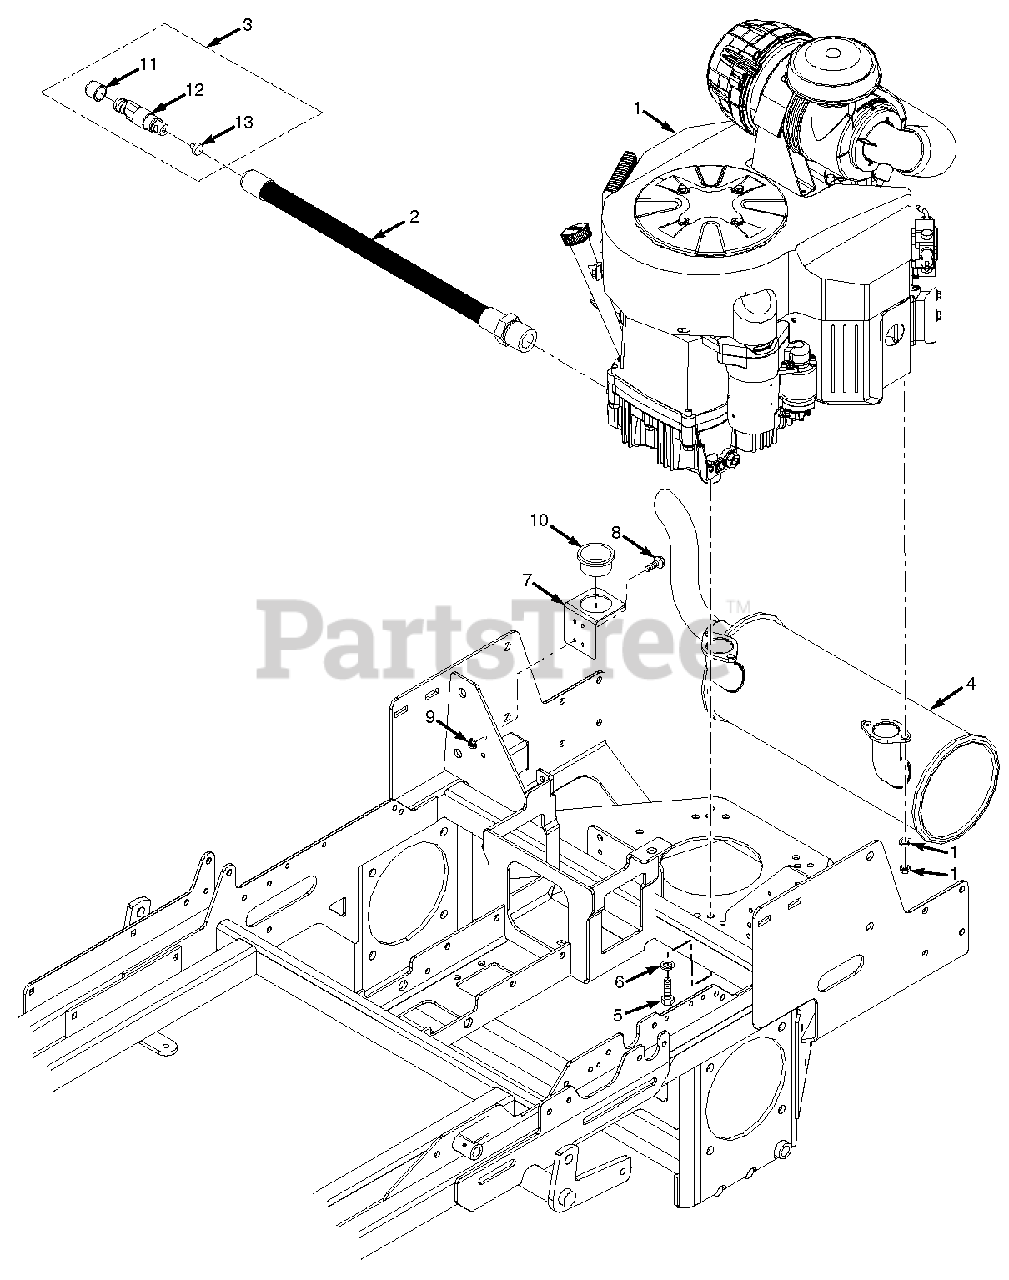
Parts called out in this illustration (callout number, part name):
1	Engine, Kawasaki 27FX (FX850)
1	Engine, Kohler 31CV-EFI (ECV860)
1	Engine, Kawasaki 31FX (FX921)
1	Engine, Kohler 35CV-EFI (ECV940)
2	Hose, Oil Drain, Kawasaki
2	Hose, Oil Drain, Kohler - ECV860
2	Hose, Oil Drain, Kohler - ECV940
3	Valve Assembly, Oil Drain
4	Muffler, Kawasaki FX850 - SCZ
4	Muffler, Kohler (ECV860)- SCZ
4	Muffler, Kawasaki FX921 - SCZ
4	Muffler, Kohler (ECV940)- SCZ
5	Bolt, Hex Head 3/8-16 x 1-1/4"
6	Lockwasher, 3/8" Spring
7	Bracket, Oil Drain Hose
8	Screw, #8-32 x 1/2"
9	Nut, Elastic Stop #8-32
10	Bushing, Thick Panel Snap
12	O-Ring
